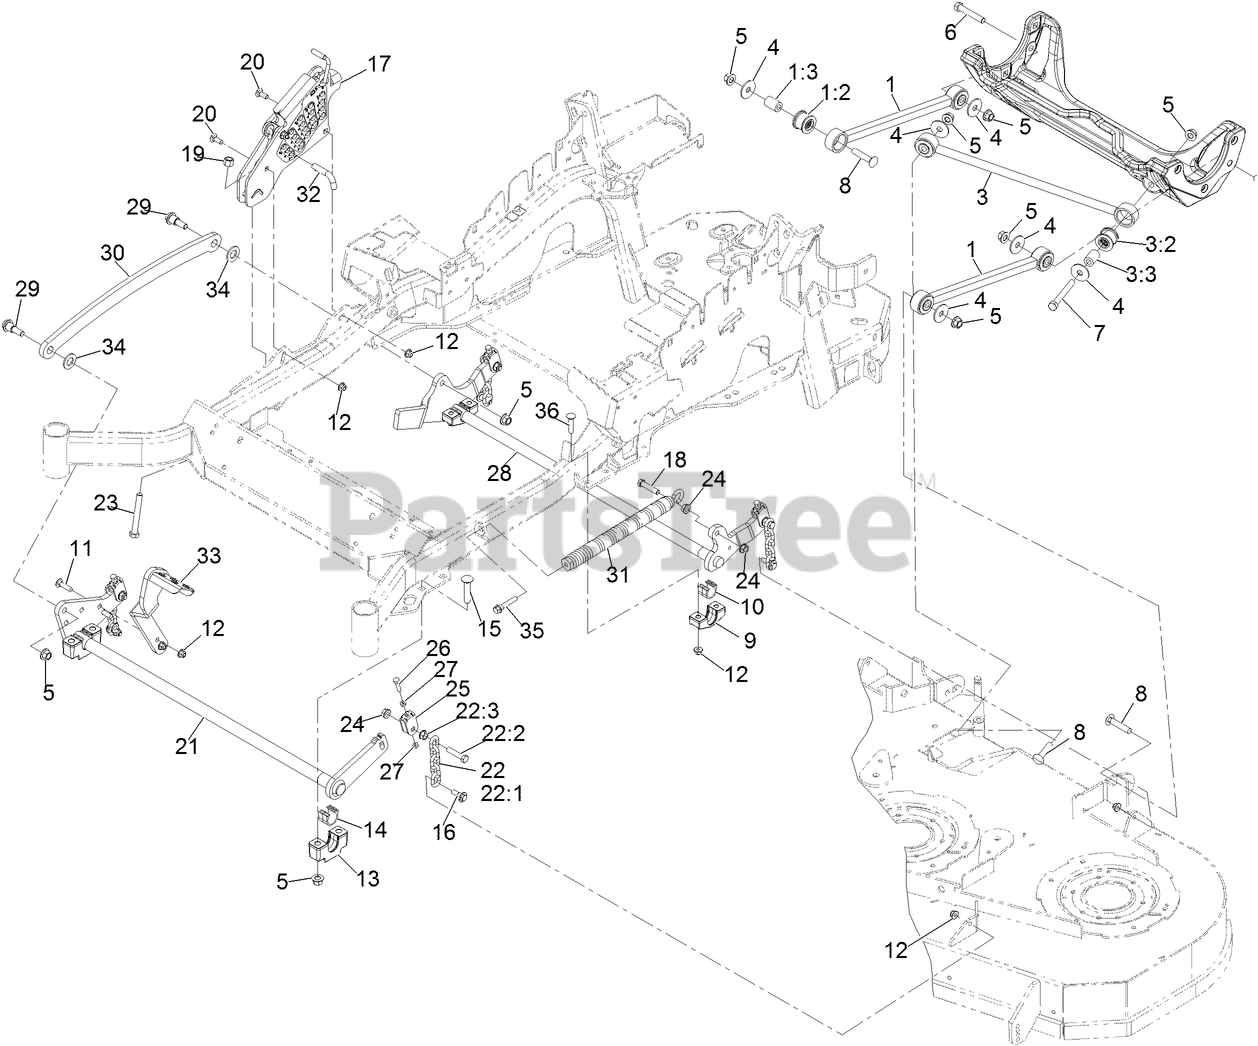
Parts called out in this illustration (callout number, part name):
1	LONG STRUT ASM
1:2	BUSHING-SUSPENSION, RUBBER
1:3	SPACER
3	PANHARD ROD ASM
3:2	BUSHING-SUSPENSION, RUBBER
3:3	SPACER
4	WASHER-THRUST
5	NUT-LOCK
6	SCREW-HH
7	SCREW-HH
8	SCREW-CARR
9	SUPPORT-CROSS SHAFT, BEARING REAR
10	BEARING-CROSS SHAFT, REAR
11	SCREW-CARR
12	NUT-HF, NI
13	SUPPORT-CROSS SHAFT, BEARING
14	BEARING-CROSS SHAFT, FRONT
15	BOLT-CARR
16	SCREW-SHOULDER, HHF
17	HOC ASM
18	SCREW-HH
19	NUT-LOCK, NI
20	BOLT-CARR
21	DECKLIFT-FRONT
22	DECK LIFT CHAIN ASM
22:1	CHAIN-LIFT, DECK
22:2	SCREW-HH
22:3	NUT-HF
23	BOLT-TAP
24	NUT-HF
25	YOKE-ADJUST, DECK
26	SCREW-HH
27	NUT-JAM
28	LIFT-DECK, REAR
29	SCREW-SHOULDER, HHF
30	LINK-LIFT, DECK
31	SPRING-EXTENSION
32	PIN-HOC
33	LEVER-FOOT
34	WASHER-FLAT
35	BOLT-SHOULDER
36	SCREW-CARR
